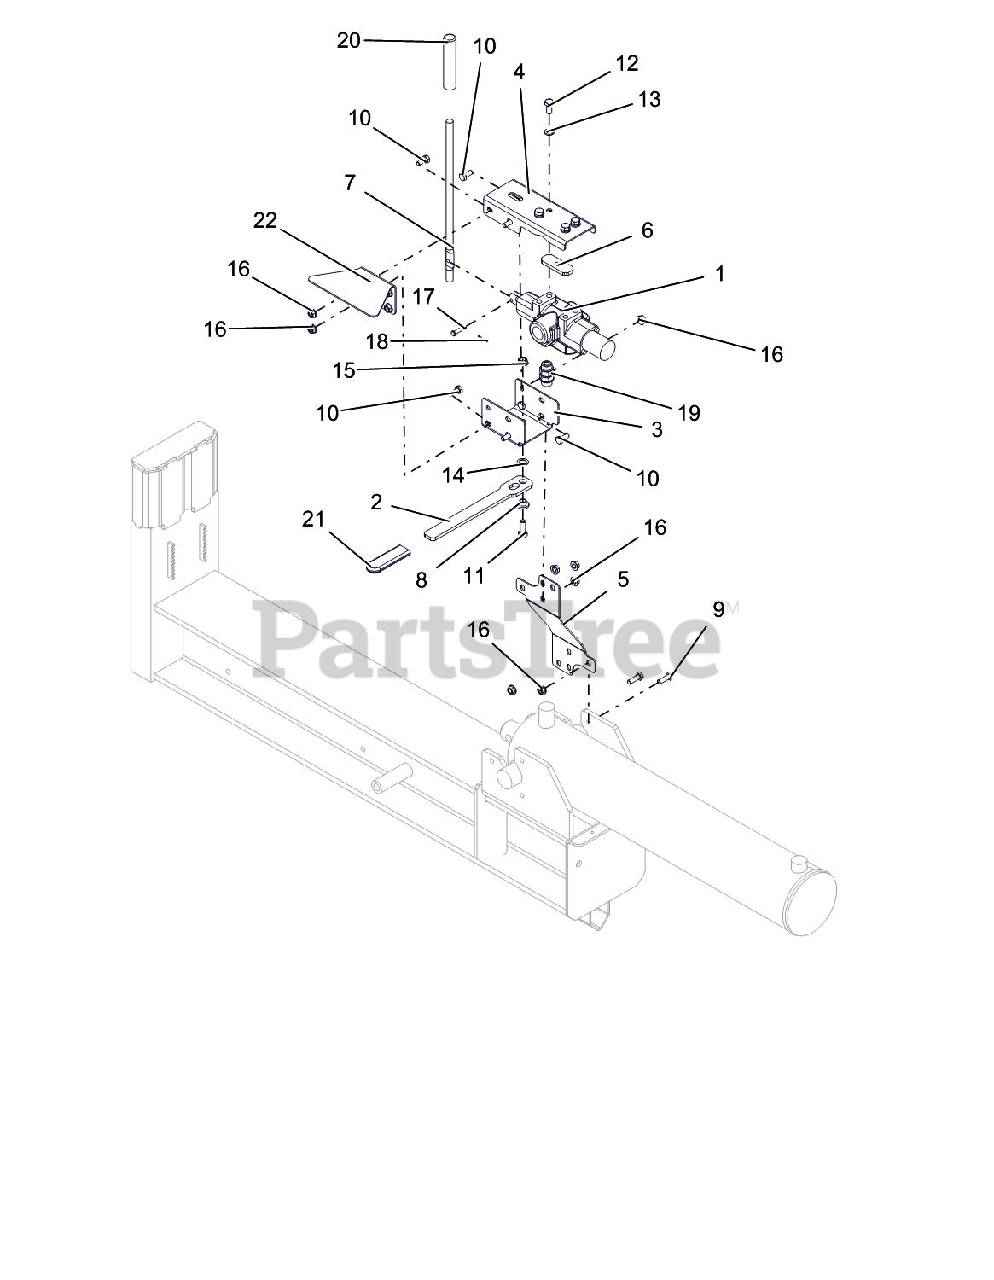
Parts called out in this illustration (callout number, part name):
1	VALVE, CONTROL - CE SPLITTER
2	HANDLE,SIDE 2 HAND CONTROL
3	BRKT, LOWER 2 HAND CONTROL
4	BRKT, UPPER 2 HAND CONTROL
5	BRACE, SIDE 2 HAND CONTROL
6	SPCR, BRKT 2 HAND CONTROL
7	HANDLE, UPPER 2 HAND CONTROL
8	BSHG-FLG .385X.500X.875X.406
9	@BLT-HEX .31-18X1.00 GR5 YWZC
10	@BLT-HEX .31-18X.75 GR5 YWZC
11	@BLT-HEX .38-16X1.00 GR5 YWZC
12	@BLT-HEX .38-16X.75 GR5 YWZC
13	@WSHR-LK .38X.094 REG YWZC
14	WSHR-FL-STL .520X.810X.033YWZC
15	@NUT-LK-TOP-FLG .38-16 YWZC
16	@NUT-LK-TOP-FLG .31-18 YWZC
17	PIN, CLEVIS - 1/4 X 1-1/8
18	@PIN-CTR .06X.75 EXTPRSQCT YWZ
19	FTG, HYD - STR 08MAORB-08MORB
20	GRIP, .475 ID X 4.25 LG
21	GRIP,HANDLE
22	CONTRL BRKT W/SAFTY DECAL-27CE
